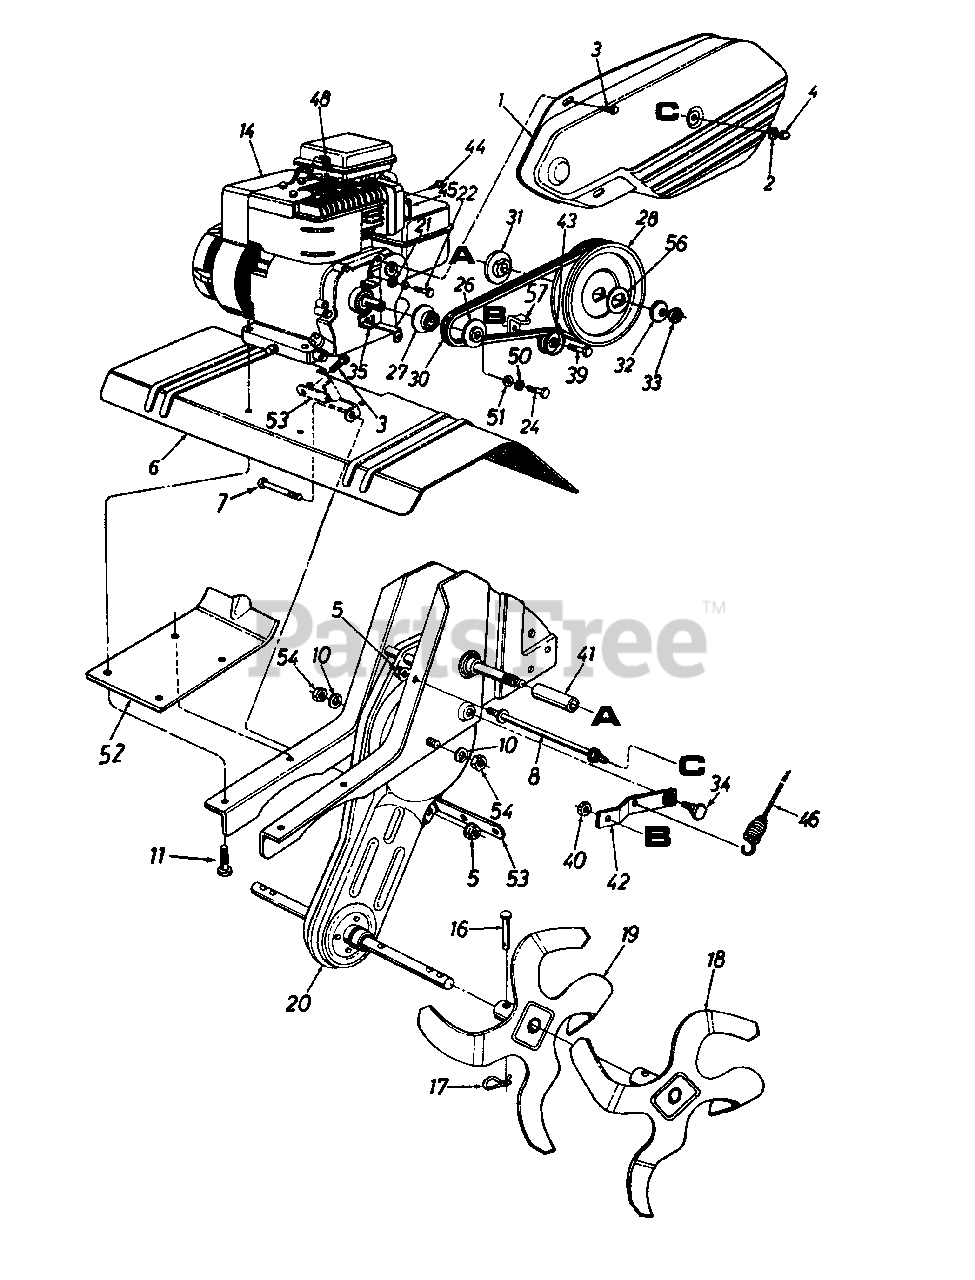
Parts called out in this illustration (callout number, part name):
2	Fl-Wash..266" I.D. x .625" O.D.
3	Hex Wash. Hd. TT-Tap Scr. 1/4-20 x .5" Lg.
4	Hex L-Stop Nut 1/4-28 Thd.
5	Hex Flange Top L-Nut 5/16-18 Thd. (Gr. 5)
8	Belt Cover Bolt
10	L-Wash. 7/16" I.D.
11	Hex Wash. Hd. TT-Tap Scr. 3/8-16 x 1.25" Lg.
14	Engine
16	Clevis Pin .375" Dia. x 1.62" Lg.
17	Internal Cotter Pin
20	Chain Case Ass'y. Comp.
21	L-Wash. 5/16" I.D.
22	Hex Bolt 5/16-24 x .5" Lg.
24	Hex Bolt 3/8-24 x 1.25" Lg.
26	Outer Engine Pulley Half
27	Inner Engine Pulley Half
28	Fl-Pulley 6" Dia.
30	"V"-Belt
31	Pulley Mounting Adapter
32	Bell-Wash. .535" I.D. x 1.5" O.D.
33	Hex Jam Nut 1/2-20 Thd. (Gr. 5)
34	Shld. Bolt 5/16-18 Thd.
39	Hex Cap Bolt 3/8-16 x 1.25" Lg.
40	Hex Cent. Jam Nut 3/8-16 Thd.
41	Spacer .64" I.D. x 2.4" Lg.
43	Fl-Idler
44	Hex Self-Tap Scr. #8-32 x .38" Lg.
45	Muffler Deflector
46	Clutch Control Cable
48	Spark Plug Boot
50	L-Wash. 3/8" I.D.
51	Fl-Wash. 3/8" I.D. x 1" O.D.
54	Hex Nut 7/16-20 Thd.
56	Bearing Retainer Washer
57	Belt Keeper
